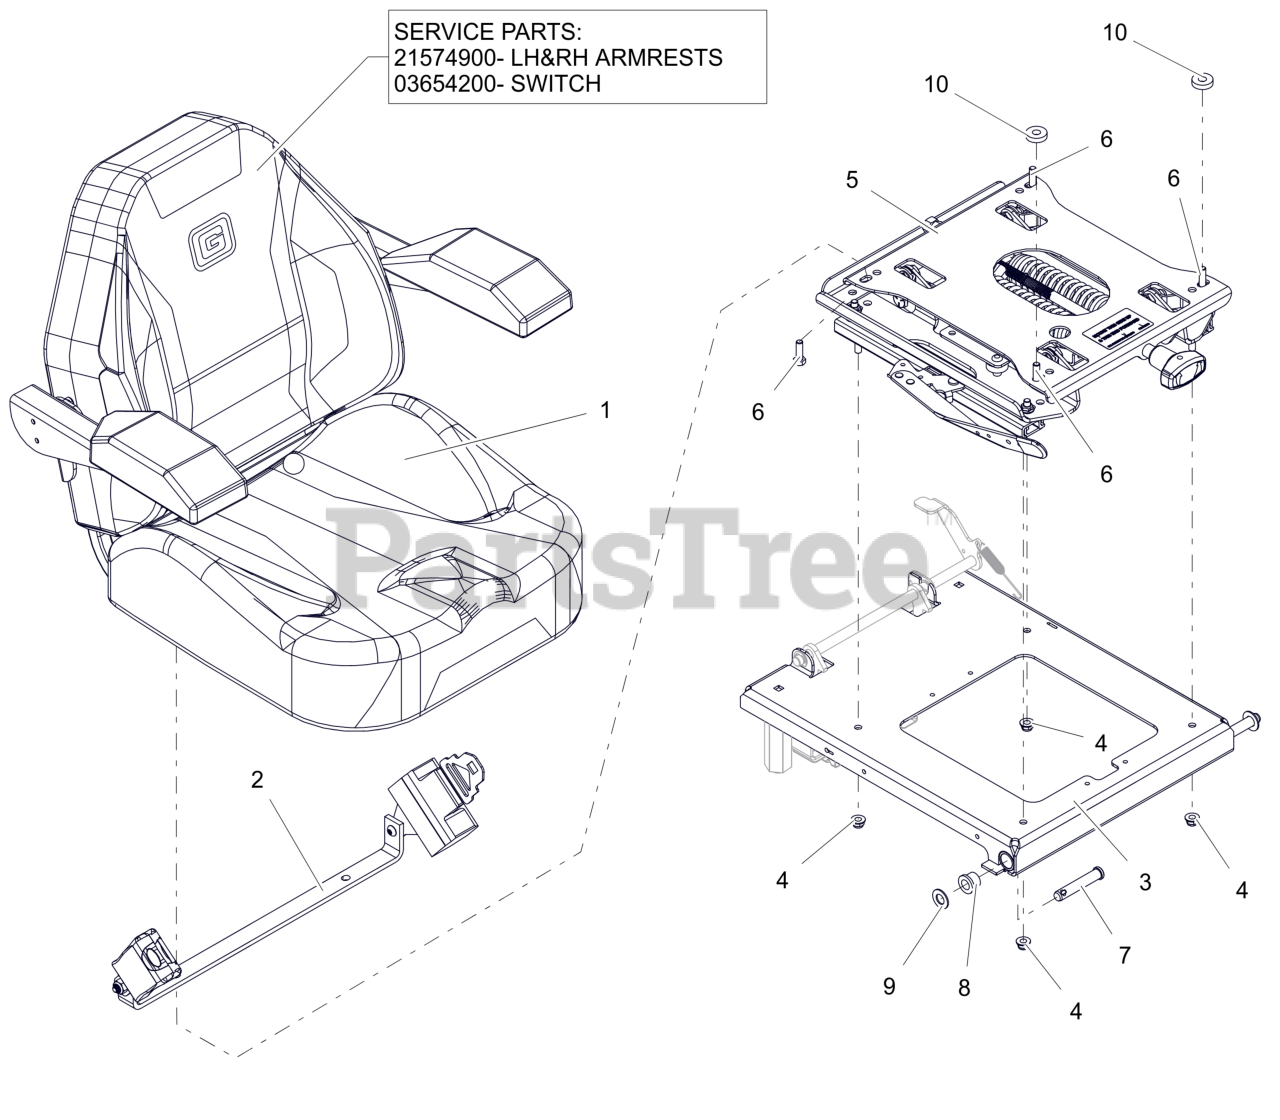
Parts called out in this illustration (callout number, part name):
1	SEAT, HD
1	LH&RH ARMRESTS
1	SWITCH- SEAT
2	KIT-SEAT BELT REPLACE-05007300
3	WLDMT, SEAT PLATE (BLACK)
4	NUT,NYL-FLG .31-18 GF ZCC
5	SUSPENSION, ULTRA LOW W/ SLIDES
6	BLT,HEX .31-18X1.00 G5 ZCC
7	PIN, SLIC-.500X42.70X2.31 -ZC
8	BSHG, FLG .516X.750X.625X.937
9	WSHR, FLT .531X1.00X.063 ZCC
10	WSHR, FLT .390X1.00X.250 ZCC
